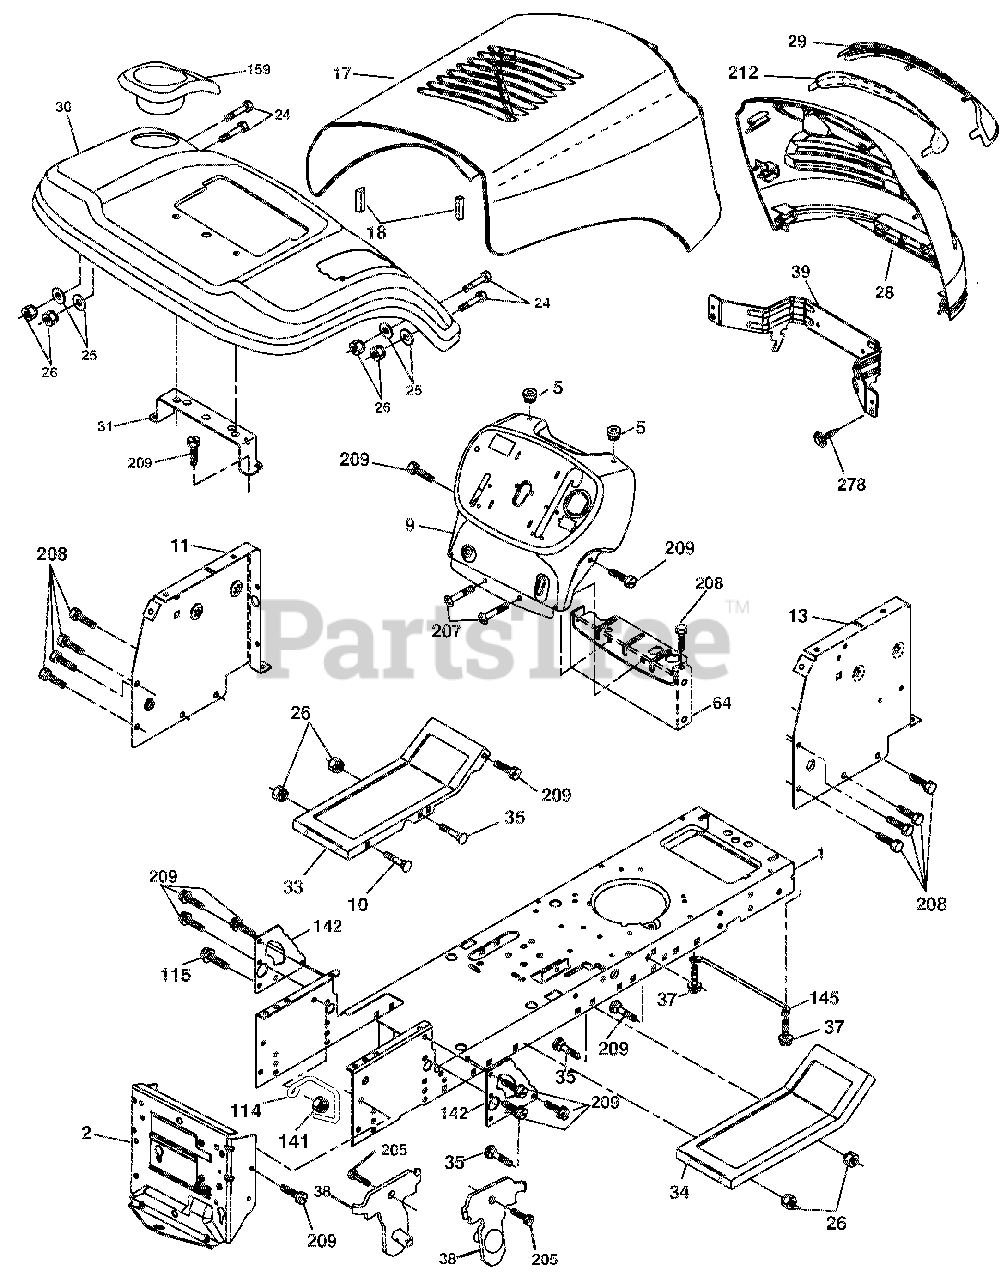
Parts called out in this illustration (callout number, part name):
1	Chassis
2	Drawbar, Stretch
5	Bumper, Hood/Dash
10	Panel Slkscr Dash RH
11	Panel Dash LH
13	PANEL.SLKSCR.DASH.RH
18	BUMPER.HOOD.LARGE. 1.75"
24	Bolt Fin Hex 3/8-16 unc x 1 Gr
25	Washer 13/32 x 13/16 x 12 Ga.
26	Locknut, Washer Insert 3/8-16
29	LENS.GRILLE.BAR
30	FENDER
31	Bracket Fender Repl 109873X
33	FOOTREST LH
34	FOOTREST RH
35	Bolt Rdhd Sht Sqnk 3/8-16 x 3/
37	SCREW.THDROL.5/16-18 X 1/2TYTT
38	Bracket Asm. Pivot Mower
39	Bracket Pivot
64	Dash Lower
114	KEEPER.BELT.REAR
115	Screw 3/8-16 x <
141	Nut, Hex, Flangelock 3/8-16
142	Plate Reinforcement
145	ROD.PIVOT.HOOD
159	CUPHOLDER
205	Screw Thdrol 3/8-16 x 1/2
207	Screw 5/16-18 x 1/2
208	SCREW.THDROL.3/8-16X1/2.TYT.BL
209	SCREW.HEXWSH THDR3/8-16X3/4.BL
212	Insert Lens Reflect
